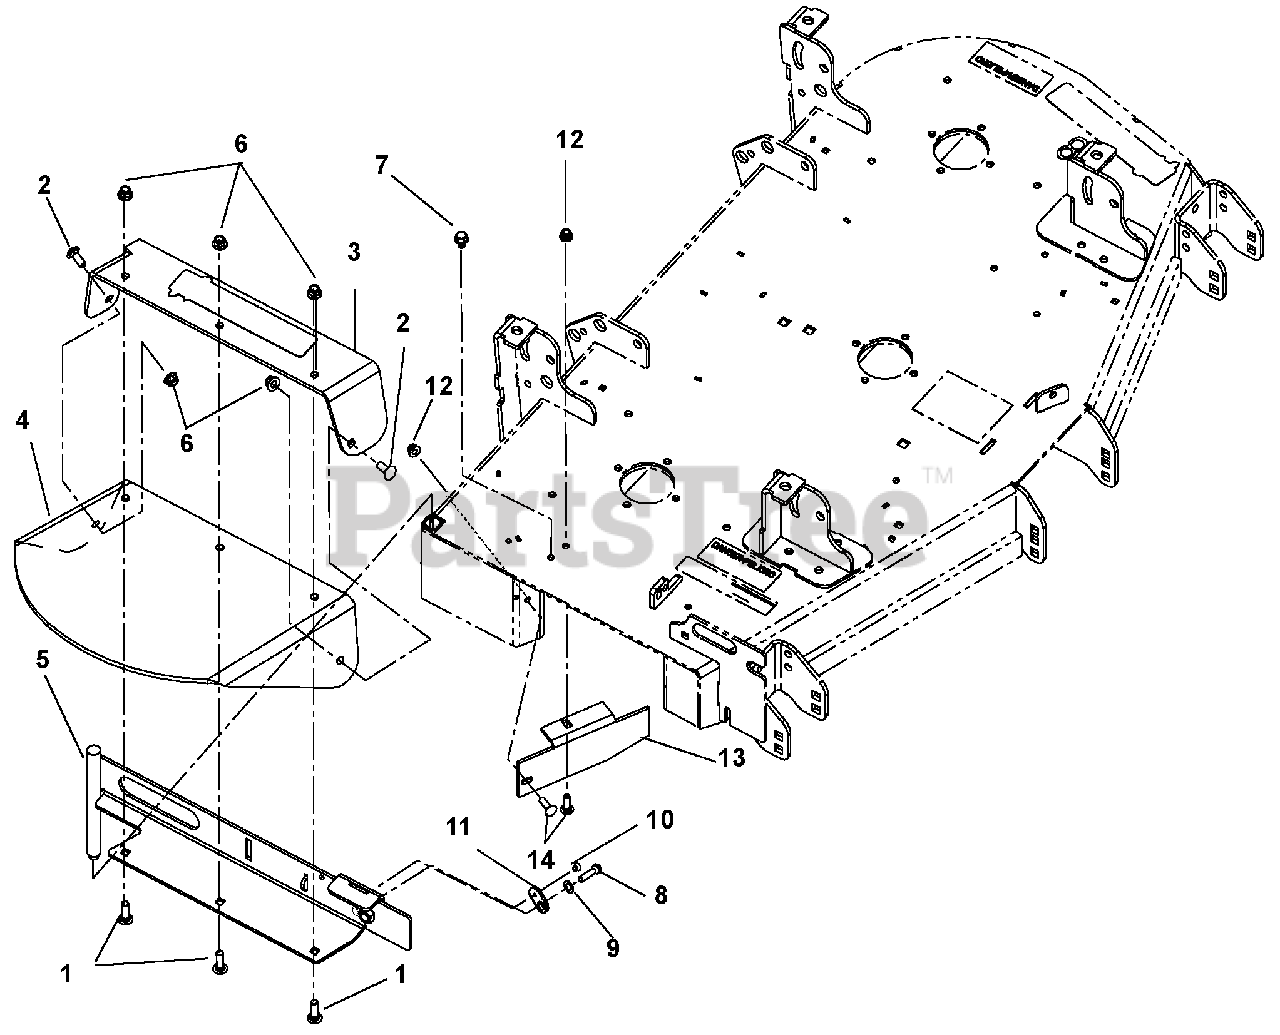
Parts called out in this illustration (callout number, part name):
1	Bolt, Round Head Square Neck .38 - 16 x 1.25
2	Bolt, Round Head Square Neck .38 - 16 x 1.00
3	Rubber Discharge Chute Support
4	Chute, Rubber Discharge
5	Weldment, 48" Discharge Chute Mounting, CE
6	Nut, Locking, Nylon, Flange .38 - 16
7	Screw, Self Tapping .38 - 16 x .50
8	Bolt, Hex .38-16 x 1.25
9	Washer, Locking, EXT.391 x .682 x .036
10	Rivet, Pop .187
11	Keeper, Bolt
12	Nut, Locking Nyloc Flange .31 - 18
13	Discharge Baffle
14	Bolt, Round Head Square Neck .31 - 18 x 1.00
